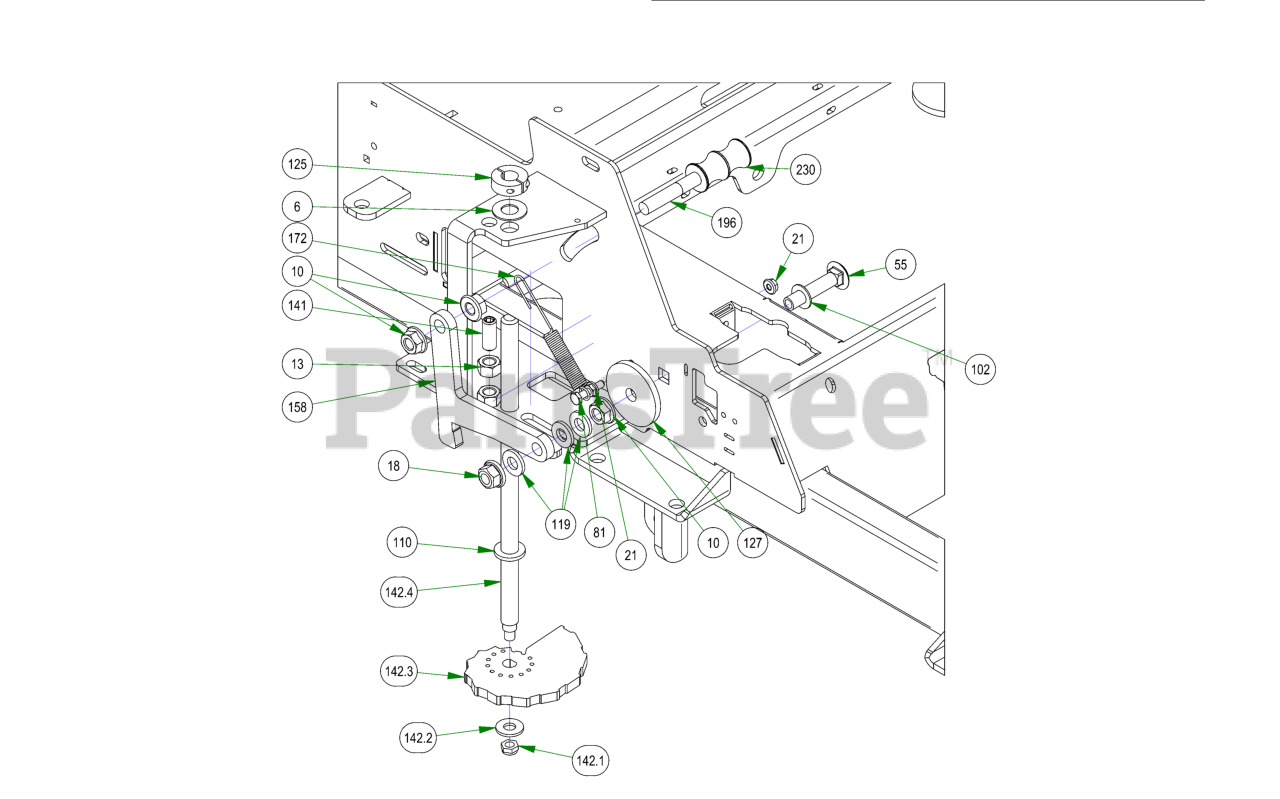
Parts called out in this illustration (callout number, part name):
6	.625 ID x 1.250 OD x .062 THK F/W Nylon
9	3/8-16 NYLON INSERT FLANGE LOCKNUT (GR.F) ZINC
10	1/2-13 HEX SERRATED FLANGE NUT HARD/ZINC
13	1/2-13 HEX NUT ZINC
18	1/2-13 NYLON INSERT FLANGE LOCKNUT ZINC
21	1/4-20 HEX SERRATED FLANGE NUT HARD/ZINC
22	5/16-18 HEX SERRATED FLANGE NUT HARD/ZINC
51	Pillow Block Assembly
51.1	Two Piece Pillow Block
51.2	Two Piece Pillow Block Strap
55	2 1/2 x 1/2 Carriage Bolt
76	13mm Damper Ball Stud-Steering
77	10mm Damper Ball Stud-XP Linkage
78	5/8 X 5/8 SOCKET SHOULDER BOLT ZINC YELLOW
79	1/2-13 NYLON INSERT JAM LOCKNUT ZINC
81	1/4-20 X 1-1/4 HEX CAP SCREW (GR.5) ZINC
84	1/2-13 X 4 HEX CAP SCREW (GR.8) ZINC YELLOW
86	3/8-16 X 1-1/4 CARRIAGE BOLT ZINC
102	.517 SQ WDTH ID X .937 OD X .060 THICK F/W PHOS/OIL
110	.635 ID X 1.120 OD X .140 THICK FLAT WASHER NYLON
119	.505 ID X 1.000 OD X .125 THICK FLAT WASHER NYLON
125	5/8" Split Collar
127	MZ Deck Idler Spacer
134	Knurled Pedal
141	Dial Rod Plunger
142	2019 Outlaw Gen2 Deck Height Dial Rod Assy
142.1	3/8-24 Nylon Insert jam locknut
142.2	3/8" Flat Washer
142.3	2019 Deck Height Cam
142.4	2019 Outlaw Gen2 Dial Rod
143	2019 Outlaw Actuator - Front
144	2019 Outlaw Actuator - Rear
146	2019 Actuator Linkage – Right – Black
147	2019 Actuator Linkage - Left - Black
155	Foot Lift Upright Lever
158	2019 Outlaw Deck Travel Lock
163	.627 ID X .753 OD X .500 LGTH X 1.000 FLG OD X .094 FLG
172	Brake Spring
182	Deck Hanger Assembly
182.1	1/2-13 HEX SERRATED FLANGE NUT HARD/ZINC
182.2	1/2-13 NYLON INSERT FLANGE LOCKNUT ZINC
182.3	1/2-13 X 2-1/4 HEX CAP SCREW (GR.5) ZINC
182.4	.505 ID X 1.000 OD X .125 THICK FLAT WASHER NYLON
182.5	Deck Hangar
196	Seat Bracket Pin
197	Security Ring - PC744
199	Foot Pedal Knob 1/2-13
230	Travel Lock Rubber Grip
235	2023 Rogue Frame - Painted
258	200 lb Gas Spring- 54" Deck outlaw
259	250lb Gas Spring - 61" Deck
260	300lb Gas Spring - 72" Deck
281	2019 Rogue Cooler Cover Decal
